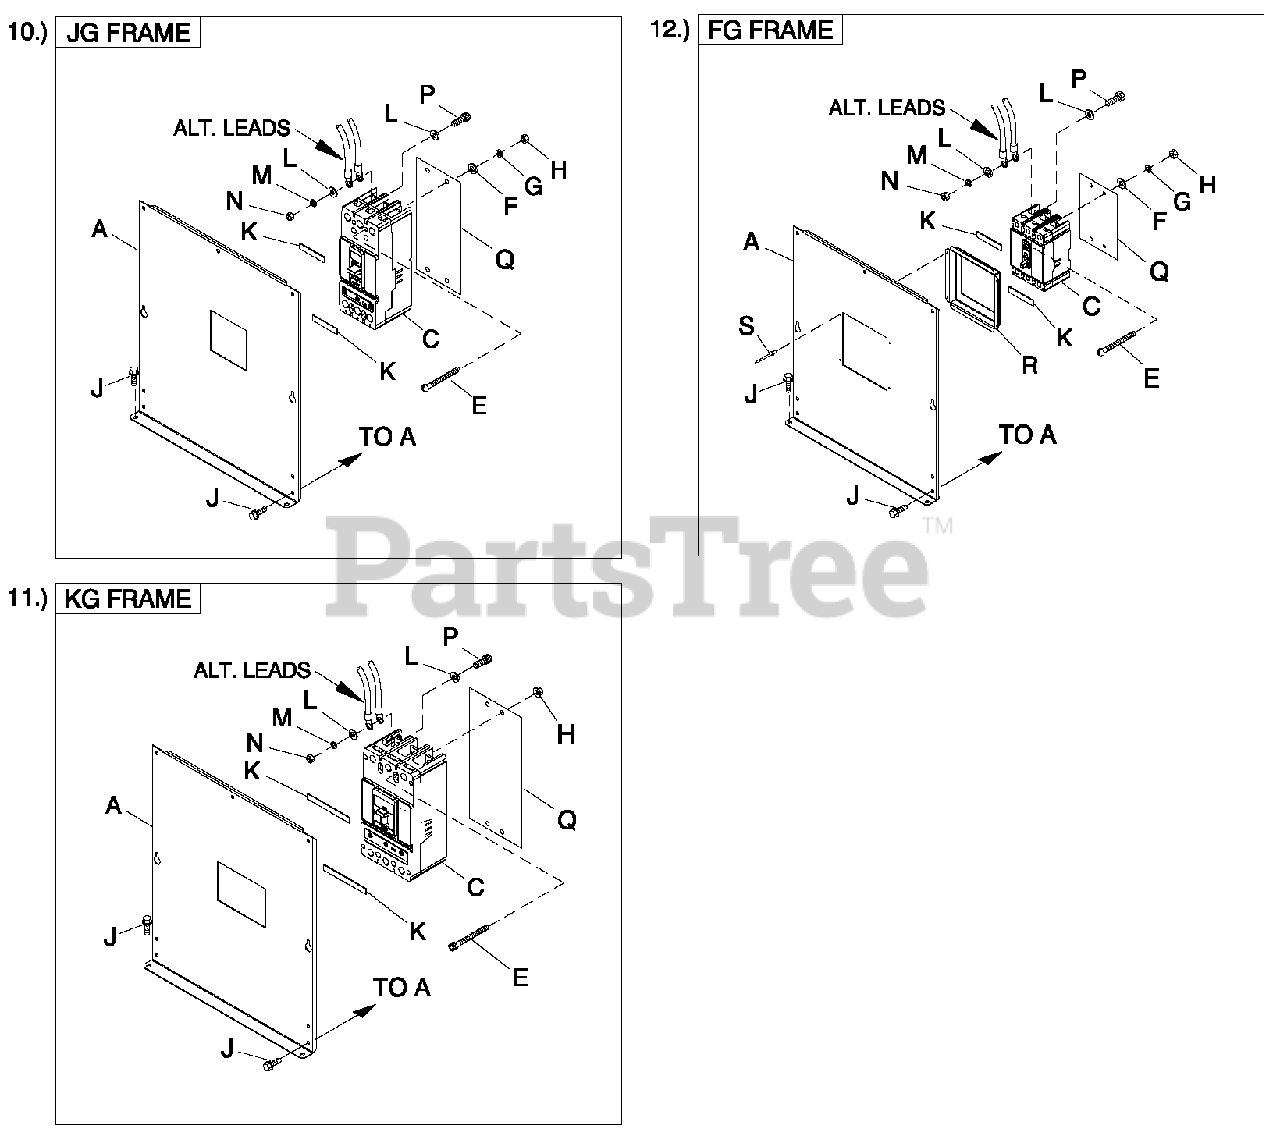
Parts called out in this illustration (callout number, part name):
10	UL CIRCUIT BREAKER (JG)
11	UL CIRCUIT BREAKER (KG)
12	UL CIRCUIT BREAKER (3P FG)
A	COVER JG E C B C 2 STAND
C	CB 0250 3P 600V E JG LL
E	SCREW RHM 1/4-20X3
F	WASHER FLAT 1/4-M6 ZINC
G	WASHER LOCK M6-1/4
H	NUT HEX 1/4-20 STEEL
J	SCREW THF M6-1 X 16 N WA Z/JS
K	TAPE ELEC 1/2 FOAM
L	WASHER FLAT 5/16-M8 ZINC
M	WASHER LOCK M8-5/16
N	NUT HEX M8-1.25 G8 CLEAR ZINC
P	SCREW SHC M8-1.25X20G8
Q	INSULATOR C B E 3 P JG
A	COVER KG E C B C 2 STAND
C	CB 0300 3P 600V E KG LL
E	SCREW SHC M6-1.0X50 C8.8
H	NUT FLANGE M6-1.0 NYLOK
Q	INSULATOR C B E 3 P KG
A	COVER C B G 225AFC2-C4
C	CB 0060 3P 480V E FG LL
E	SCREW PPHM #8-32X 1-3/4ZINC
F	WASHER FLAT #8 ZINC
G	WASHER LOCK #8-M4
H	NUT HEX #8-32 STEEL
L	WASHER FLAT #10 ZINC
M	WASHER LOCK M5
N	NUT HEX M5-0.8 G8 CLEAR ZINC
P	SCREW HHC M5-0.8X 20 G8.8
Q	INSULATOR CB 3P E TYPE CC/FG
R	COVER CB DISH 3P E FD
S	RIVET PO P .125 X .275 SS
